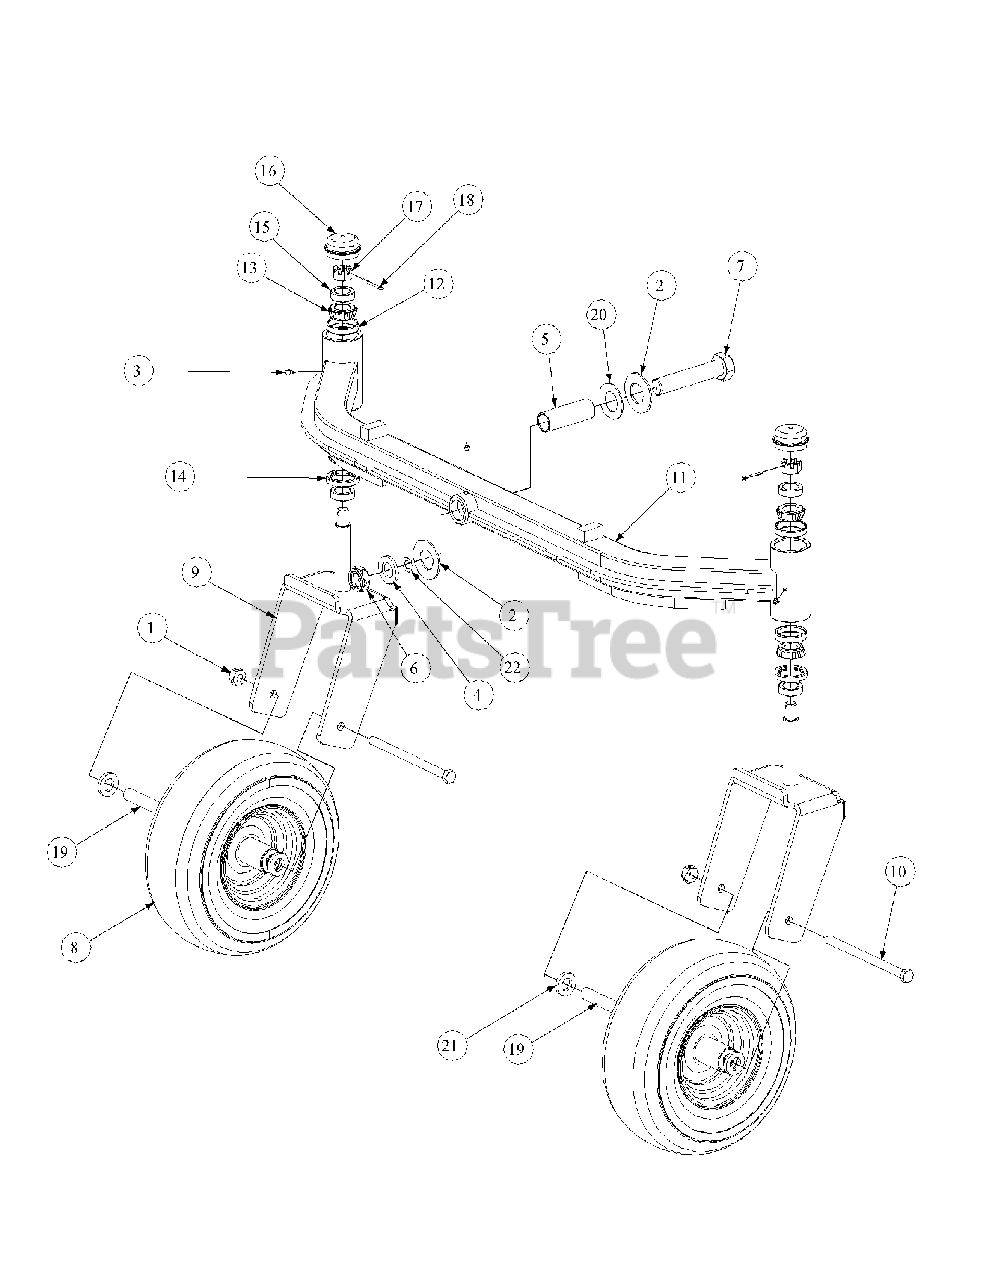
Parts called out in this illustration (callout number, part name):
1	Nut, 1/2-20, Center Lock
2	Bell Washer, 1.25 ID x 2.5 OD x .180
3	Grease Fitting
4	Special Washer
5	Spacer, 1.005 ID x 1.25 OD x 3.6
6	Nut, Jam, 1.0-14, Insert Lock
7	Hex Cap Screw, 1-14 x 5.0
7	Retainer Extension Self Locking
8	Wheel Assembly, 13 x 6.50 x 6, White, includes:
9	Yoke, Caster Wheel
10	HHCS, 1/2-20, 7.50
11	Front Axle Assembly
12	Cup Bearing
13	Bearing Cone
14	Seal
15	Ring Seal
16	Grease Cap, 1.986 OD
17	Slotted Nut, 3/4-16
18	Cotter Pin, 5/32, 1.25
19	Wheel Spacer
20	Flat Washer, 1.25 ID x 2.25 OD x .075
21	Spacer, .812 ID x .218LG
22	Retainer Extension, Self Locking
